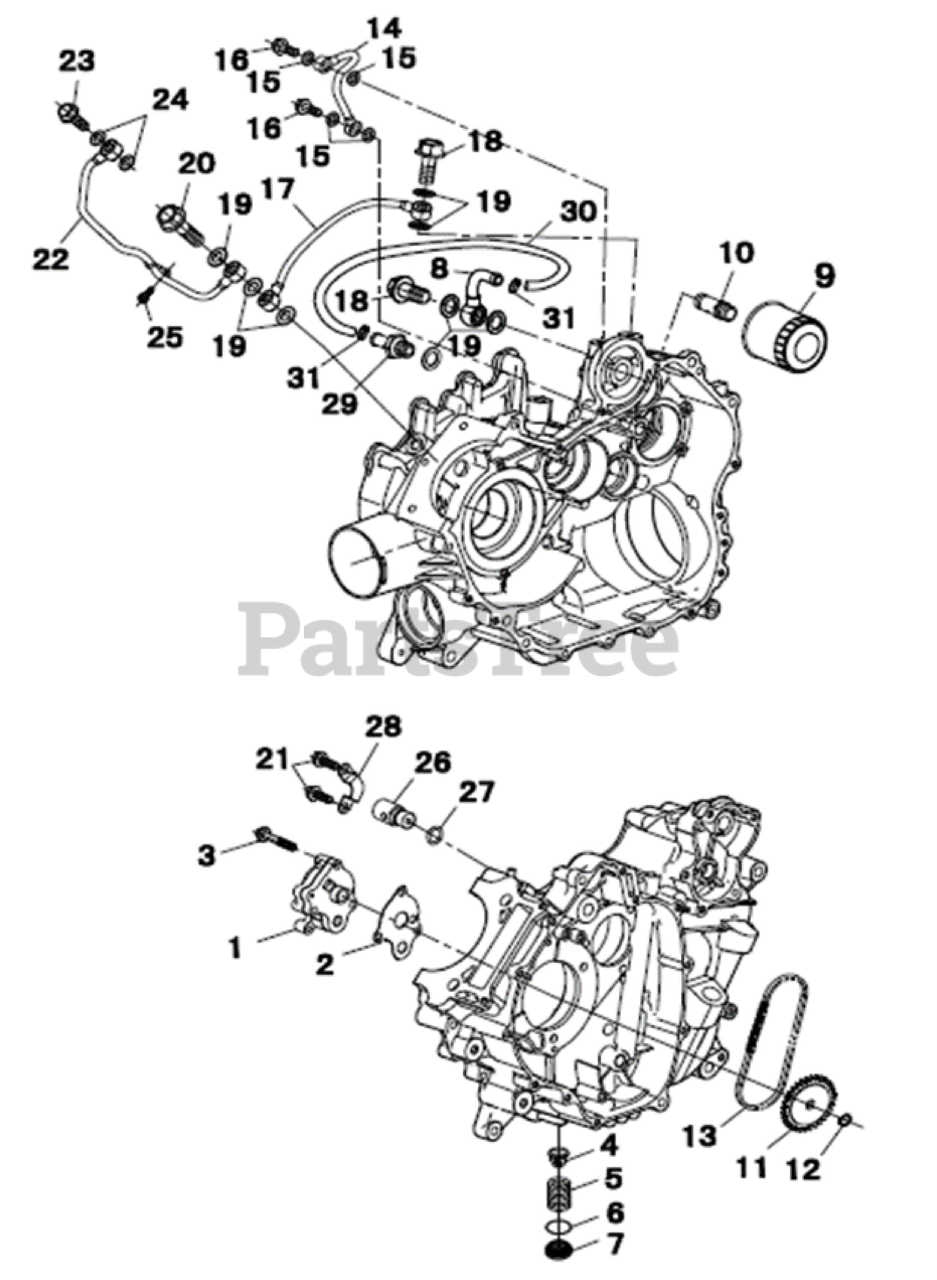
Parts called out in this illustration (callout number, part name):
1	Oil Pump Assy
2	Gasket,Oil Pump
3	Hexagon flange bolts M6X40
4	Oil Filter Strainer
5	Filter Spring
6	O-Ring 36X3.5
7	Blind Nut,Oil Drainage
8	Oil Tube Welding Assy D
9	Oil Filter
10	Filter joint
11	Oil Pump Driven Sprocket
12	Circlip for shaft 11
13	Chain,Oil Pump
14	Oil Tube Welding Assy A
15	Aluminum Washer 8X15X2
16	Bolts for oil tube M8X25
17	Oil Tube Welding Assy B
18	Bolts for oil tube M14X1.5X28
19	Aluminum Washer 14X22X1.5
20	Bolts for oil tube M14X1.5X50
21	Hexagon flange bolts M6X14
22	Oil Tube Welding Assy C
23	Bolts for oil tube M10X1.25X30
24	Aluminum Washer 10X16X1.2
25	Hexagon flange bolts M6X12
26	Pressure Regulating Valve Assy,Engine Oil
27	O-Ring 10X2.45
28	Press Plate,Pressure Regulating Valve
29	Oil Pipe Joint
30	Rubber Oil Pipe 1080
31	Hose Clamp Assy 12?20
